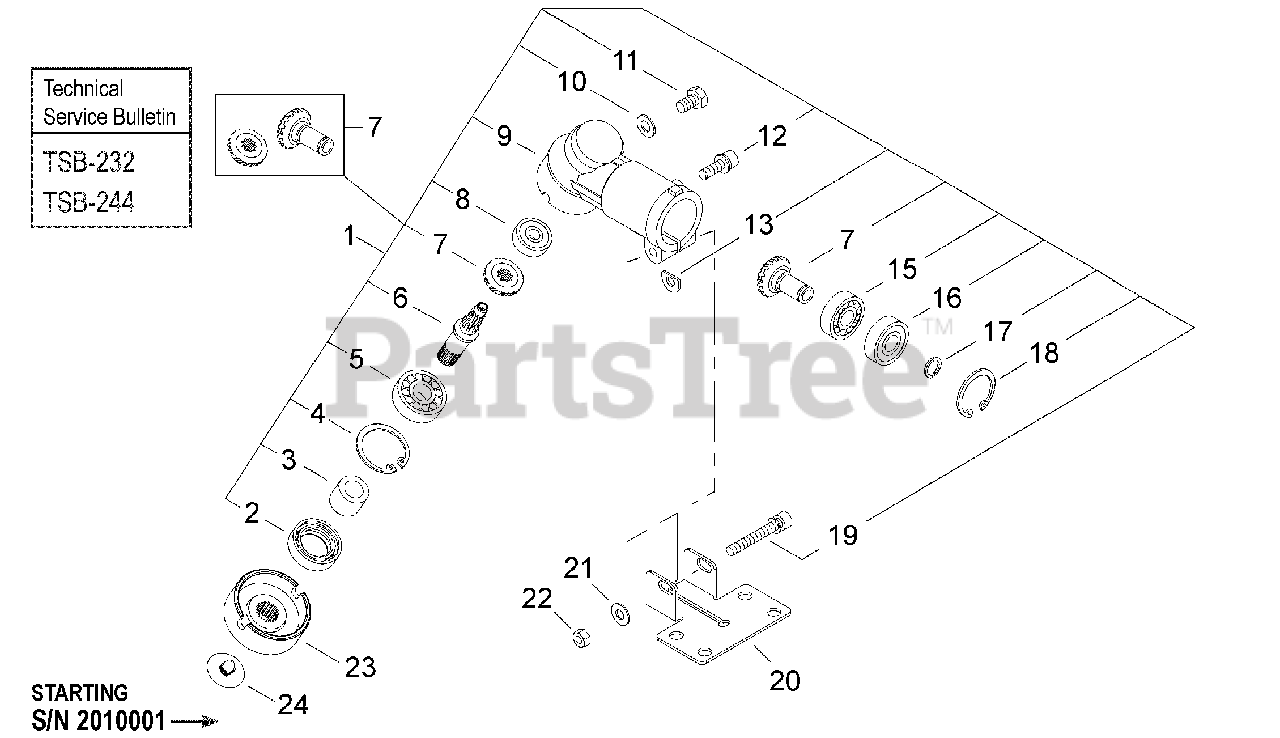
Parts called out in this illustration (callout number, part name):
1	GEAR CASE ASSY
2	SEAL, OIL
3	SPACER
4	RING, SNAP Ø28
5	BEARING, BALL 6001
6	SHAFT, GEAR
7	GEAR SET
8	BEARING, BALL 608 DDU
9	HOUSING, GEAR CASE
10	WASHER 6.5×11.5×0.8
11	BOLT M6×10
12	BOLT M5×16
13	D-WASHER
15	BEARING, BALL 609
16	BEARING, BALL 609ZZ
17	RING, SNAP
18	RING, SNAP Ø24
19	BOLT M5×35
20	PLATE, SHIELD MOUNTING
21	WASHER 5 MM
22	NUT M5
23	HOLDER
24	CLIP
